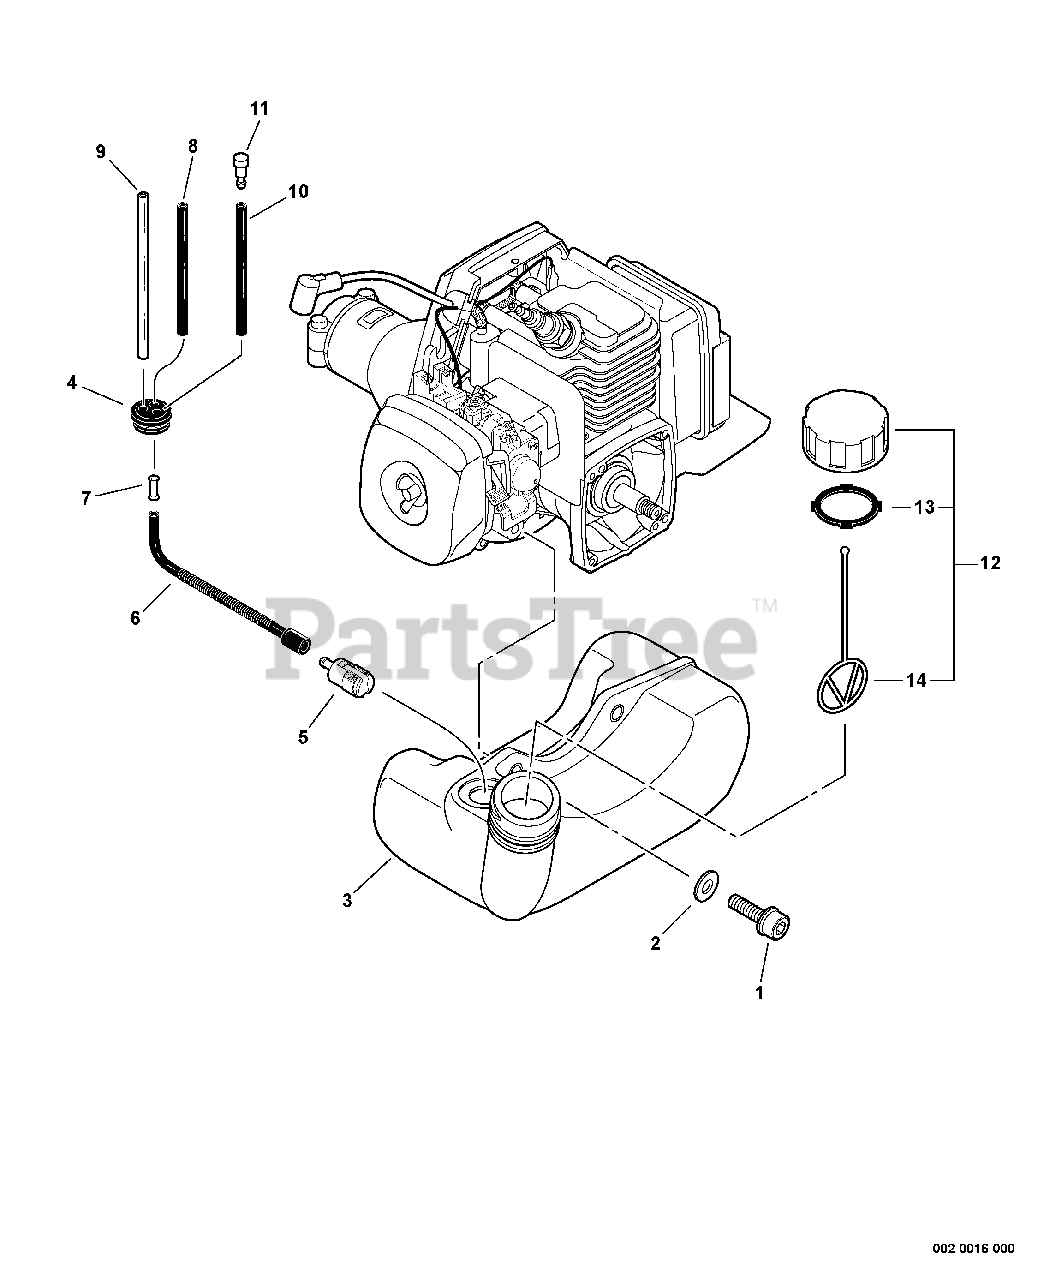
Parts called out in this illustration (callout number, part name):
1	SCREW - 5X20
2	WASHER - 5
3	TANK, FUEL
4	GROMMET
5	FILTER, FUEL
6	PIPE, FUEL - CORRUGATED
7	CONNECTOR, PIPE
8	PIPE - 3X5X70 -- BLACK
9	PIPE - 3X6X80 -- CLEAR
10	PIPE - 3X5X70 -- BLACK
11	VENT, FUEL TANK
12	CAP ASSY - ORANGE
13	GASKET, CAP
14	CONNECTOR, CAP
